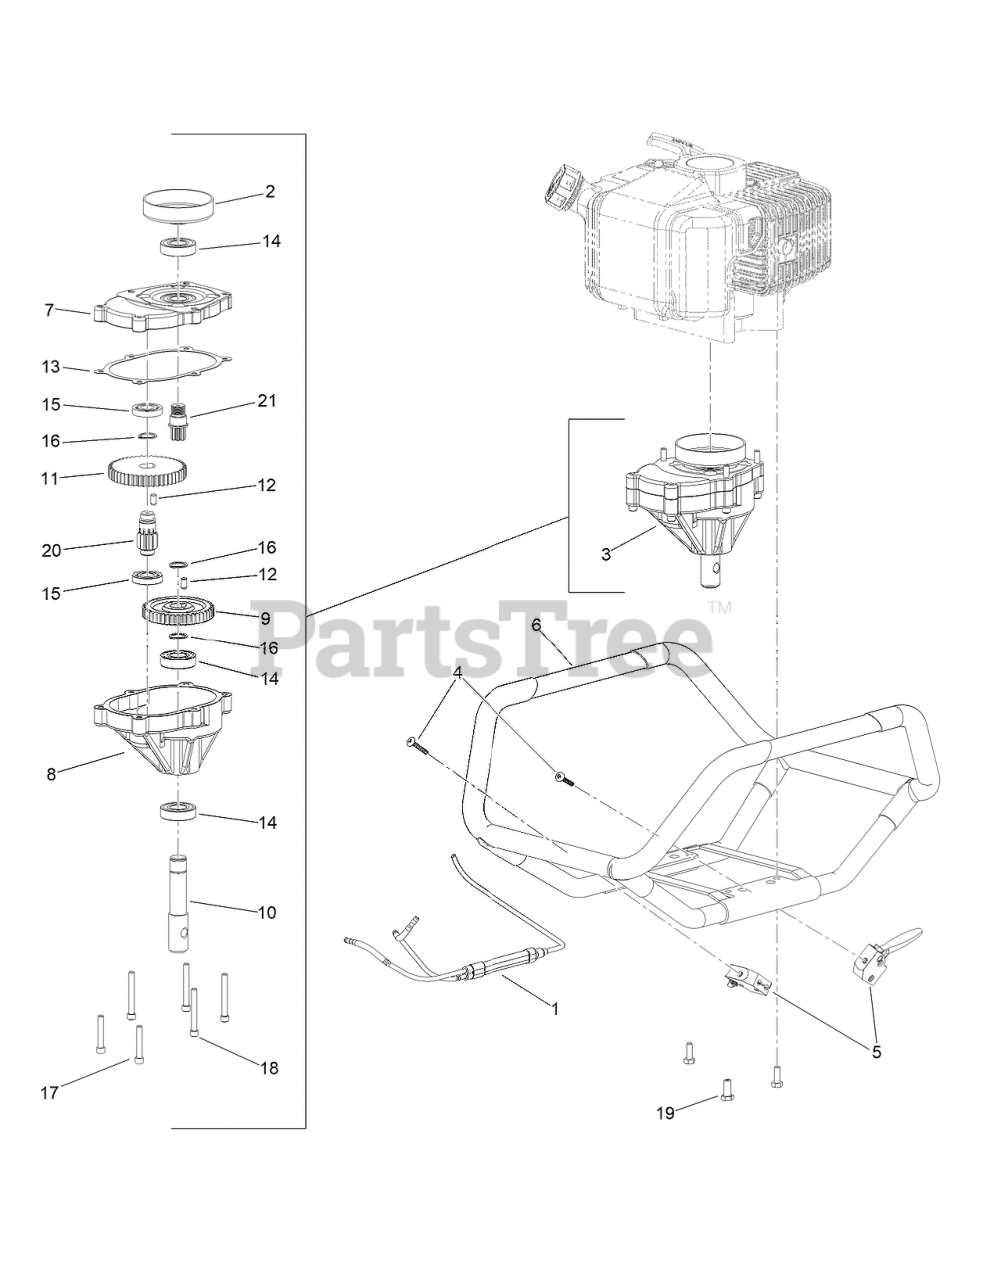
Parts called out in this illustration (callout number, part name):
1	CABLE ASM
2	DRUM-CLUTCH
3	TRANSMISSION ASM
4	SCREW-PTH
5	TRIGGER ASM
6	HANDLEBAR
7	CASE-TRANSMISSION UPPER
8	CASE-TRANSMISSION LOWER
9	GEAR-44T
10	SHAFT-OUTPUT
11	GEAR-48T
12	PIN-DOWEL
13	GASKET-TRANSMISSION
14	BEARING-BALL
15	BEARING-BALL
16	RING-RETAINING
17	SCREW-SHCS
18	SCREW-SHCS
19	SCREW-HH
20	PINION-10T
21	PINION-7T
